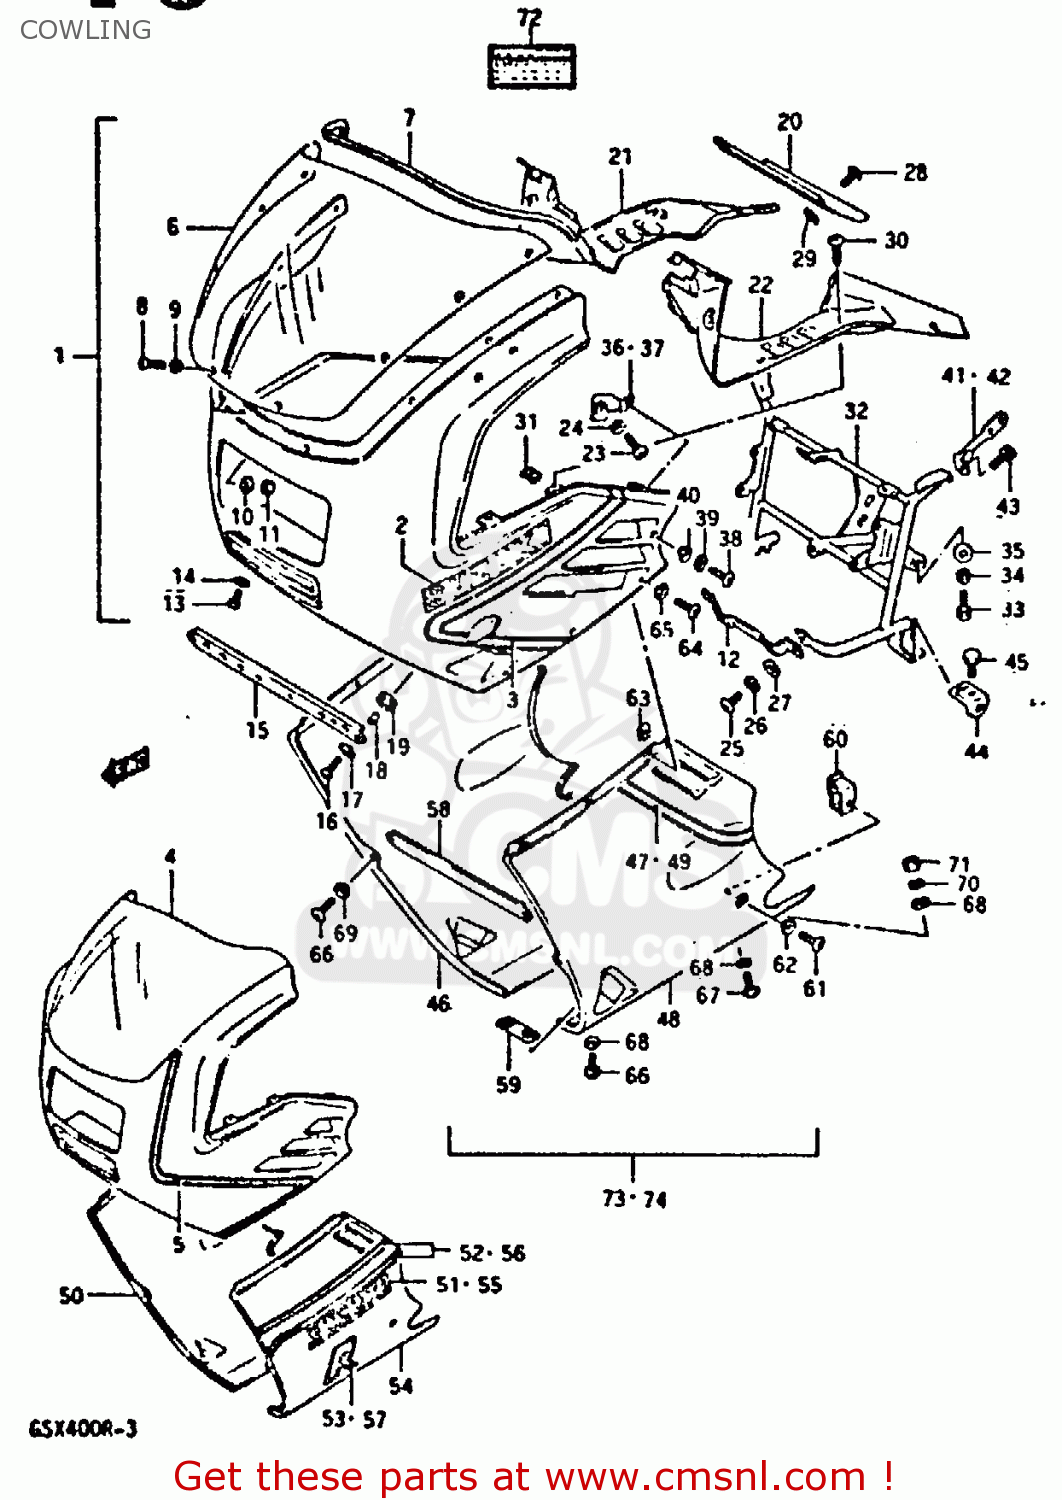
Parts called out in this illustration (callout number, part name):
1	COWLING ASSY
6	WINDOW.COWLING
7	MOLDING,SCREEN
8	SCREW(5X14)
9	CUSHION
10	WASHER,5MM
11	NUT 8MM
13	SCREW(5X14)
14	WASHER
16	SCREW, CENTER
17	WASHER (6.5X18X1.6)
18	SPACER (6.8X10X10)
19	CUSHION
20	PANEL.COWLING.U
21	PANEL.COWLING.U
22	PANEL.COWLING.U
23	SCREW(6X12)
24	WASHER
25	SCREW
26	WASHER,LOCK
27	WASHER
28	SCREW
29	NUT
30	SCREW
31	NUT
33	BOLT
34	WASHER,LOCK,8.
35	WASHER
36	BRACKET.COWLING
37	BRACKET.COWLING
38	SCREW
39	WASHER,LOCK
40	WASHER
41	BRACKET.RR VIEW
42	BRACKET COMP.RE
43	BOLT
44	PLATE,TURN SIGNAL LAMP
45	SCREW
51	EMBLEM
53	EMBLEM,COWLING LWR
55	EMBLEM
57	EMBLEM,COWLING LWR
59	PLATE, ADJUST
60	BRACKET FAIRING
61	SCREW
62	WASHER(6.5X16X1.2)
63	NUT,HEADLAMP HOUSING,UPPER
64	SCREW(5X18)
65	WASHER
66	SCREW
67	SCREW
68	WASHER
69	WASHER
70	WASHER
71	NUT
